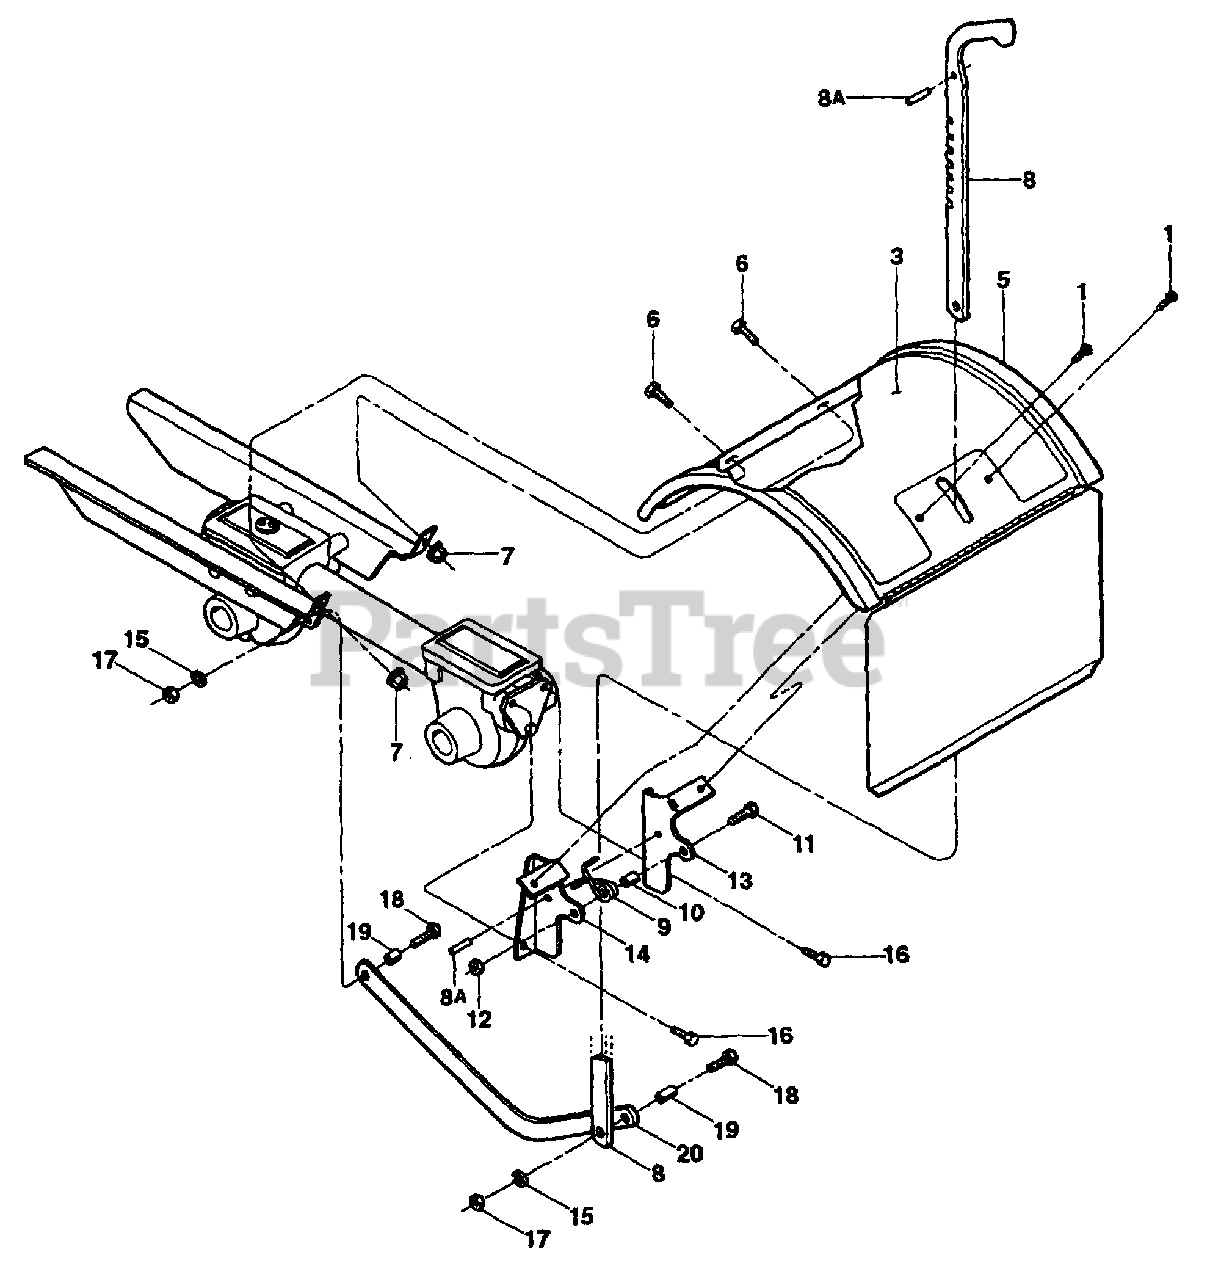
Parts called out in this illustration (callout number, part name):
1	Flange Screw, Self-Tapping, 1/4-20 x 1/2
3	Decal-Hood
5	Tine Hood.
6	Hex Screw, 5/16-18 x 1/2
7	Nut, Flange Lock, 5/16-18
8	Depth Regulator Lever
8A	Spirol Pin
9	Spring-Depth Regulator
10	Spacer
11	Hex Screw, 1/4-20 x 1
12	Locknut, 1/4-20
13	Bracket-Hood, Right Hand
14	Bracket-Hood, Left Hand
15	Lockwasher, 5/16
16	Flange Screw, 5/16-18 x 1
17	Hex Nut, 5/16-18
18	Hex Screw, 5/16-18 x 1-1/4,
19	Bushing
20	Drag Bar
